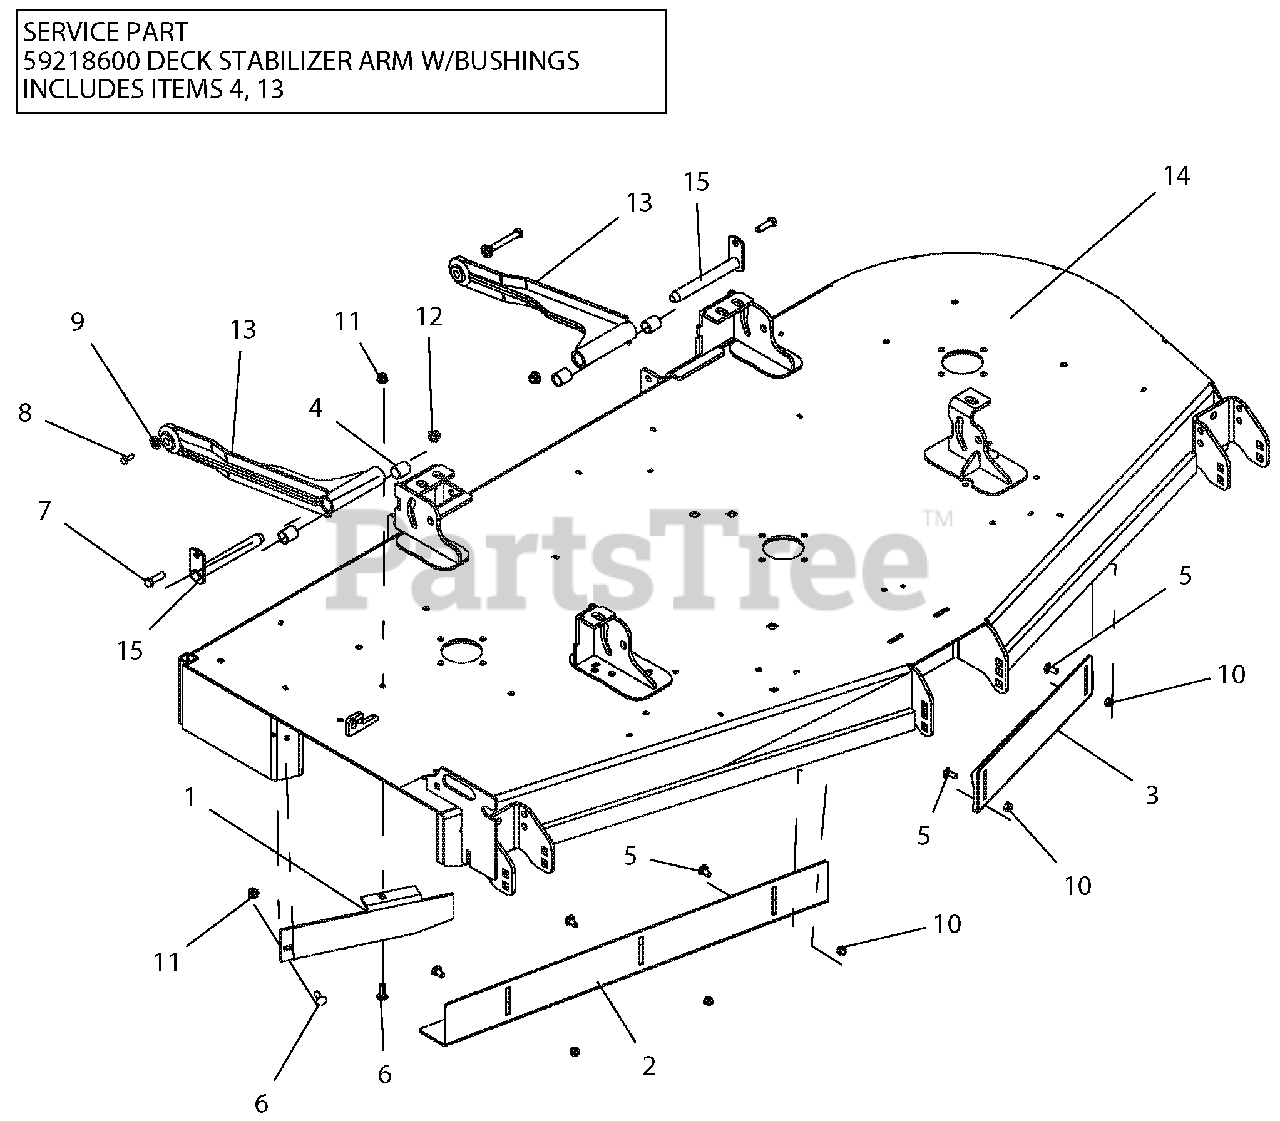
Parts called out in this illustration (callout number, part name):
1	BAFFLE, 72" DISCHARGE-RED
2	BAFFLE, 72" RH VACUUM-BLACK
3	BAFFLE, 72" LH VACUUM-BLACK
4	BRG, .75 X .875 X 1.00
5	BLT-RDHDSQNK .31-18X.75 G5 YWZC
6	BLT-RDHDSQSHNK .31-18X1.00 G5 Y
7	BLT-HEX .38-16X1.25 GR5 YWZC
8	BLT-HEX .25-20X.75 GR5 YWZC
9	WSHR-LK .50X.125 REG YWZC
10	NUT-LK-NYL .312-18 YWZC
11	NUT-LK-NYL-FLG .31-18 YWZC
12	NUT-LK-NYL-FLG .38-16 YWZC
13	DECK STABILIZER ARM W/BUSHINGS
14	72" SIDE DISCH DECK W/SAFETY DECALS
15	WLDMT, MOWER MTG. PIN
